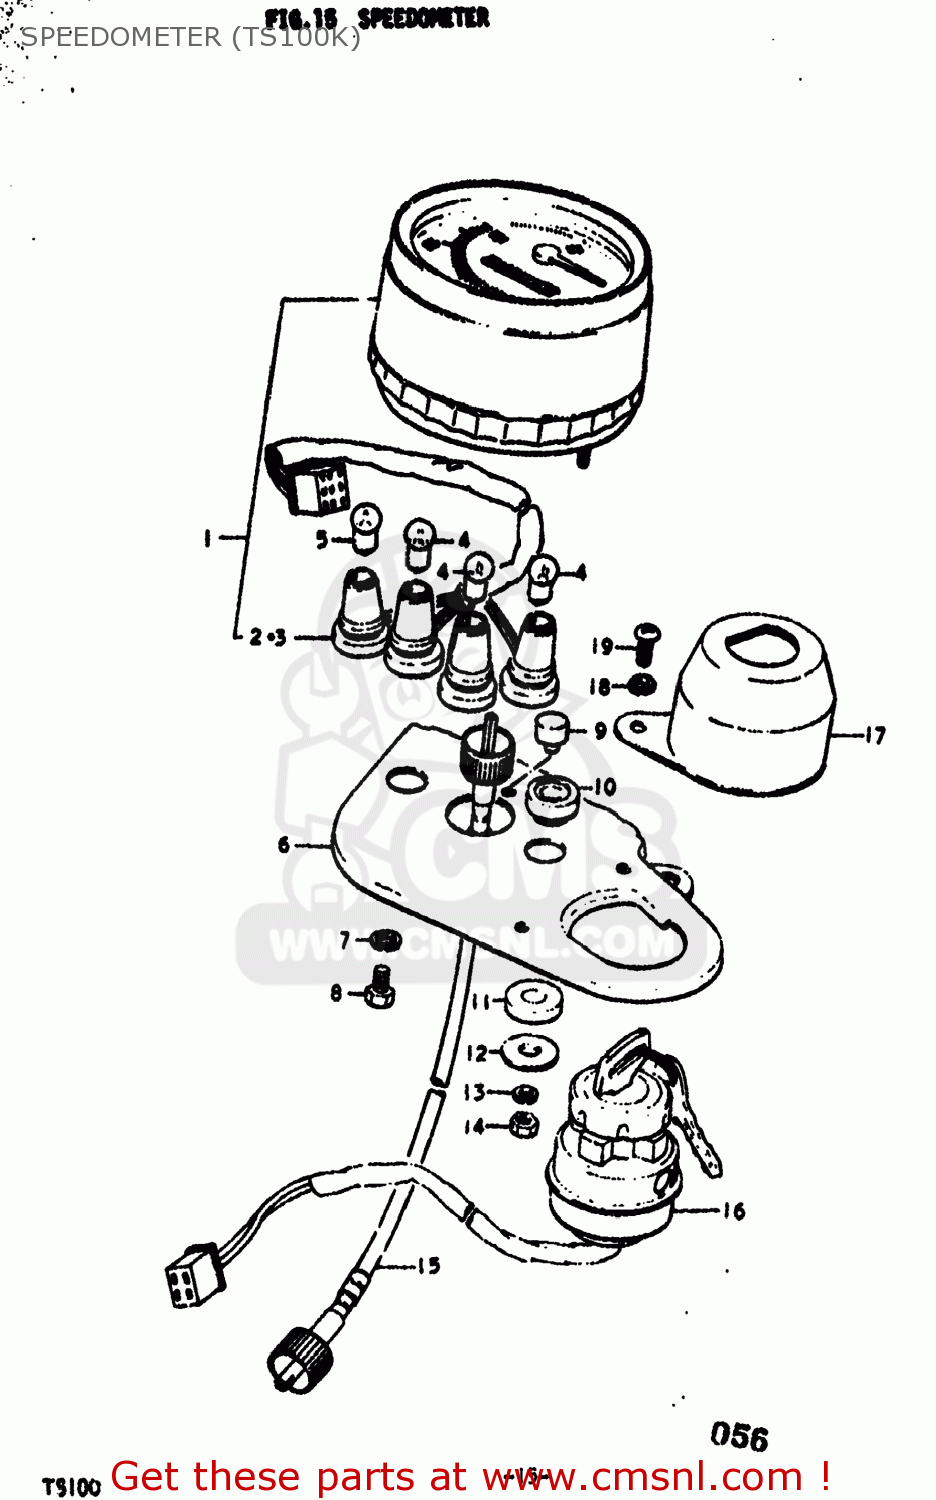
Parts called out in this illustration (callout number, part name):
1	SPEEDOMETER ASSEMBLY
2	SOCKET,METER
3	SOCKET,METER
4	BULB(6V/3W)
5	BULB(6V1.7W,STANLEY,A61A)
6	BRACKET,METER
7	LOCK WASHER
8	BOLT
9	CUSHION,METER
10	CUSHION,METER
11	CUSHION
12	WASHER(5.5X16X1.5)
13	LOCK WASHER
14	NUT
15	CABLE ASSEMBLY,SPEEDOMETER
16	SWITCH ASSEMBLY,IGNITION
17	BRACKET,IGNITION SWITCH
18	LOCK WASHER
19	SCREW
